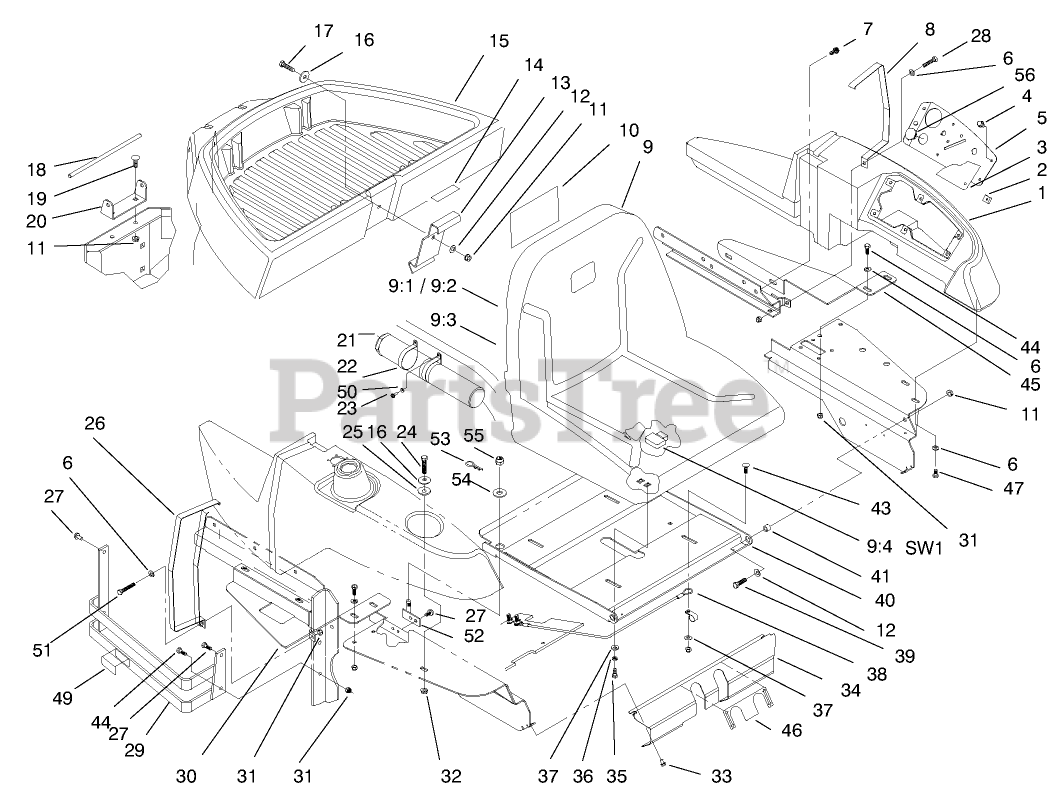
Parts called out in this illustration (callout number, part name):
1	CONSOLE
2	CLIP-TINNERMAN
3	DECAL - INSTRUMENT
4	SCREW-PPH
5	PANEL - INSTRUMENT
6	WASHER-PLAIN
7	SCREW-HWHTF
8	STRAP-CONSOLE
9	SEAT ASM
9:1	SHELL
9:2	SEAT CUSHION KIT
9:3	EDGING
9:4	SWITCH-SEAT
9:5	SCREW-HH
10	DECAL
11	NUT-LOCK, NI
12	WASHER-FLAT
13	LATCH - UTILITY BOX B
14	DECAL - NO RIDERS
15	BOX - UTILITY
16	WASHER
17	SCREW-HH
18	PIN - PIVOT,UTILITY BOX
19	BOLT-CARR
20	HINGE - DUMPBOX B
21	TUBE-MANUAL
22	CLAMP-R
23	RIVET-BLIND
24	SCREW-HH
25	BUSHING-FLANGE
26	STRAP-TANK, FUEL
27	SCREW-HWHTF
28	SCREW-HH
29	Bumper ASM
29	BUMPER ASM
30	PLATE-SUPPORT, TANK
31	NUT-LOCK, NI
32	NUT-HHF, WHIZ
33	SCREW-HWH
34	PLATE - COVER, FRONT
35	SCREW-HH
36	WASHER-LOCK
37	WASHER-FLAT
38	CABLE-SEAT
39	SCREW-HH
40	SEAT PLATE ASM
41	SPACER-WHEEL
43	BOLT-CARR
44	SCREW-HH
45	PLATE - CONSOLE SUPT R
46	DECAL - OPERATION
47	SCREW-HH
49	DECAL-HOT SURFACE
50	WASHER-FLAT
51	SCREW-HH
52	LATCH ASM
53	PIN-HAIR
54	WASHER-FLAT
56	PLUG - DOME 1.125 DIA
